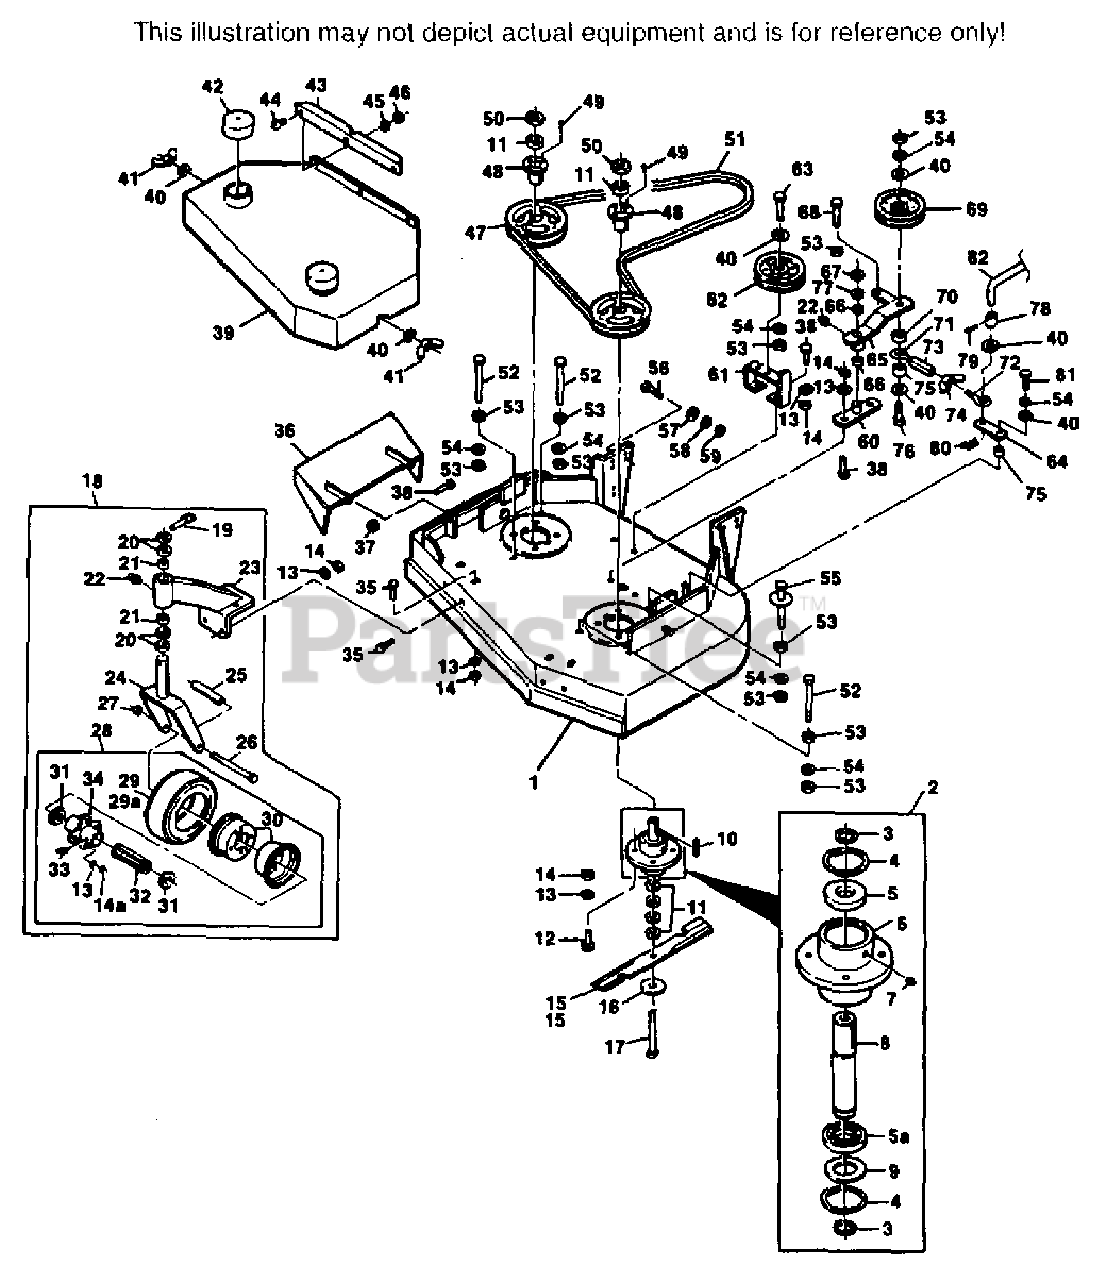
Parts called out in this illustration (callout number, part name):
1	CUTTER DECK WLD.(INCL. DECALS)
2	CUTTER SPINDLE ASSY.(INCL 3-9)
3	RETAINING RING, 1" EXT.-INVERTED
4	RETAINING RING, 2-7/16 INT-BASIC
5	BEARING, CUTTER SPINDLE
6	SPINDLE HOUSING
7	GREASE FITTING, STR. 5/16 SERR.
8	SPINDLE, CUTTER BLADE
9	WASHER, 1-15/16 X 2-13/32 X 16 GA.
10	KEY, 1/4 X 1/4 X 2
11	SPACER, CUTTER BLADE
15	CUTTER BLADE, 20" STD.
16	FLAT WASHER, 5/8W
17	HEX HEAD BOLT, 5/8-11 X 9-1/2
18	CASTER ASSY.(INCL. 19-28)
19	QUICK PIN
20	SPACER, CASTER YOKE, 1/2 LONG
21	BRONZE BEARING
22	GREASE FITTING, STR. 1/4-28
23	SUPPORT ASSY.(INCL. 21-22)
24	CASTER YOKE WLD.
25	SLEEVE, CASTER WHEEL BEARING
26	HEX HEAD BOLT, 1/2-13 X 5-1/2
28	WHEEL ASSY.(INCL. 13-14,29-34)
29	TIRE ONLY, CASTER WHEEL
29A	INNER TUBE ONLY, CASTER WHEEL
30	RIM PAIR, CASTER WHEEL
31	RETAINER, BEARING, CASTER WHEEL
32	ROLLER BEARING, CASTER WHEEL
33	GREASE FITTING, 45' 1/4-28
34	HUB ASSY. W/BOLTS, CASTER WHEEL
36	DISCHARGE CHUTE WLD.
37	HEX NUT, 5/16-18 ELASTIC STOP
39	BELT COVER ASSY.(INCL. DECALS)
40	WASHER, 25/64 X 15/16 X 12 GA.
41	WING NUT, 3/8-16
42	SPINDLE SHIELD
43	BELT COVER SKIRT
47	PULLEY(INCL. 48-49)
48	TAPER HUB
51	BELT, BLADE DRIVE
55	BELT GUIDE WLD.
57	WASHER, 15/32 X 59/64 X 16 GA.
59	HEX NUT, 7/16-14 ELASTIC STOP
60	IDLER PIVOT WLD.
61	IDLER PULLEY SUPPORT
62	PULLEY, BELT GUIDE
64	WASHER, 13/32 X 13/16 X 16 GA.
65	IDLER ARM ASSY.(INCL. 22 & 66)
66	BRONZE BEARING
67	RETAINING RING, 3/4 EXT.-"E"
69	IDLER PULLEY, BELT CLUTCH - STD.
69	IDLER PULLEY, BELT CLUTCH - WIDE
70	SPACER, IDLER
71	EYEBOLT, LH
72	EYEBOLT, RH
73	TURNBUCKLE
74	WING NUT, 5/16-18
75	SLEEVE, CAM CLUTCH
77	BLADE CLUTCH ROD
78	SLEEVE, CLUTCH ROD
80	HAIR PIN, LARGE
82	CAM LINK WLD.
